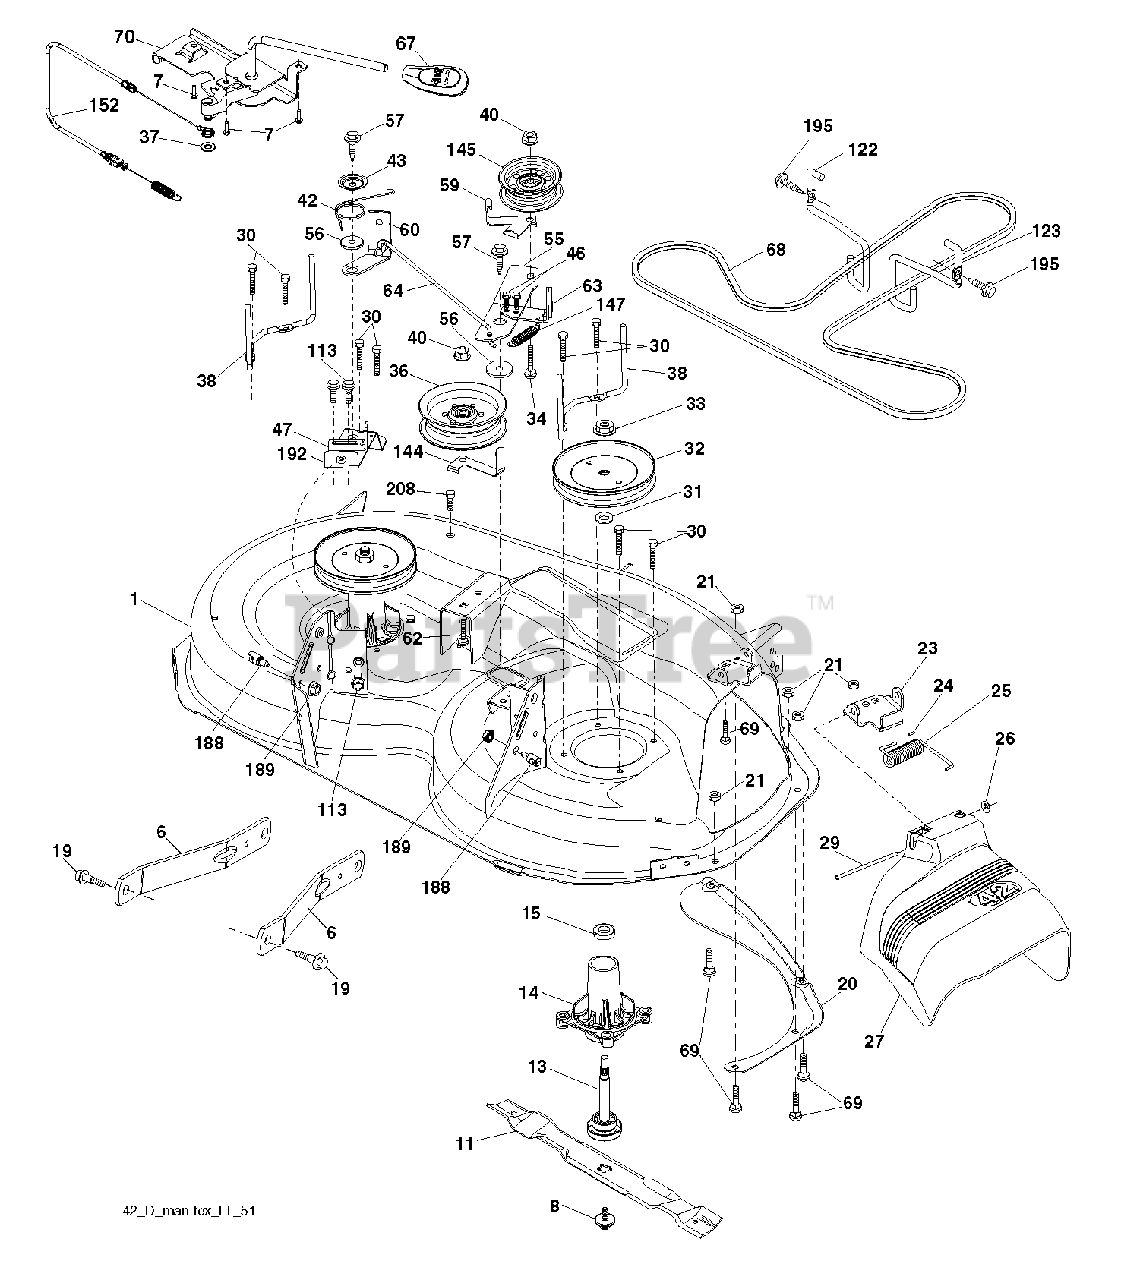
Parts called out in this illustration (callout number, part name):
6	ARM.SUSPENSION.MOWER.R
7	SCREW.#10 X 0.750.BOS (2 2)
8	BOLT.WASHER.ASM.7/16-2
11	42" HI-LIFT BLADE
13	SHAFT.ASM.MDRL.N/GREASE.38
14	HOUSING.MANDREL.4PT.
19	BOLT.SHOULDER
20	BAFFLE.VORTEX
21	LOCKNUT
23	BRKT.DEFLECTOR.38"2005+
24	CAP-SLEEVE LT
25	SPRING.TORSION.DEFLECT
26	NUT PUSH M
27	SHIELD.DEFLECTOR.MOWER.42"BLAC
29	ROD.HINGE
30	SCREW, WASHER HEAD
31	WASHER.SPACER.MANDREL
32	PULLEY.MANDREL.5.438.PD
33	NUT.FLANGE.LOCK.TOP
34	BOLT.3/8-16X1.50
36	PULLEY.IDLER.2006
38	KEEPER.BELT.MANDREL.PULLEY
40	NUT LOCK FLG 3/8-16 UNC
42	SPRING.TORSION.BRAKE
43	SRPING.TORSION.RETAINE
46	SCREW.1/4-20X5/8
47	BRKT.CLUTCH.CABLE
55	IDLER.ARM
56	SPACER.RETAINER
57	SCREW 3/8-16X1
59	GUARD, BELT
60	ARM BRAKE MOWER
62	BOLT
64	LINK BRAKE
67	HANDLE.CLUTCH.CABLE.LT
68	BELT.DECK.DRIVE.42"
69	BOLT
70	CLUTCH.ASM.MANUAL.LT.TEX
113	BOLT.5/16HEX.WHS.HD
122	KEEPER BELT ENGINE LH
123	KEEPER BELT RH
144	KEEPER.BELT.MOWER
145	PULLEY.IDLER.48"PRIMARY
147	RETURN SPRING
152	CABLE.CLUTCH.MANUAL.
188	STUD.FASTNER.W/ANTI-ROTATE
189	NUT LOCK HEX FLANGE 5/16-18
192	BRKT.BRAKE.STAND.LH.
195	SCREW, 3/8-16X3/4
208	SCREW 3/8-16X1/2
